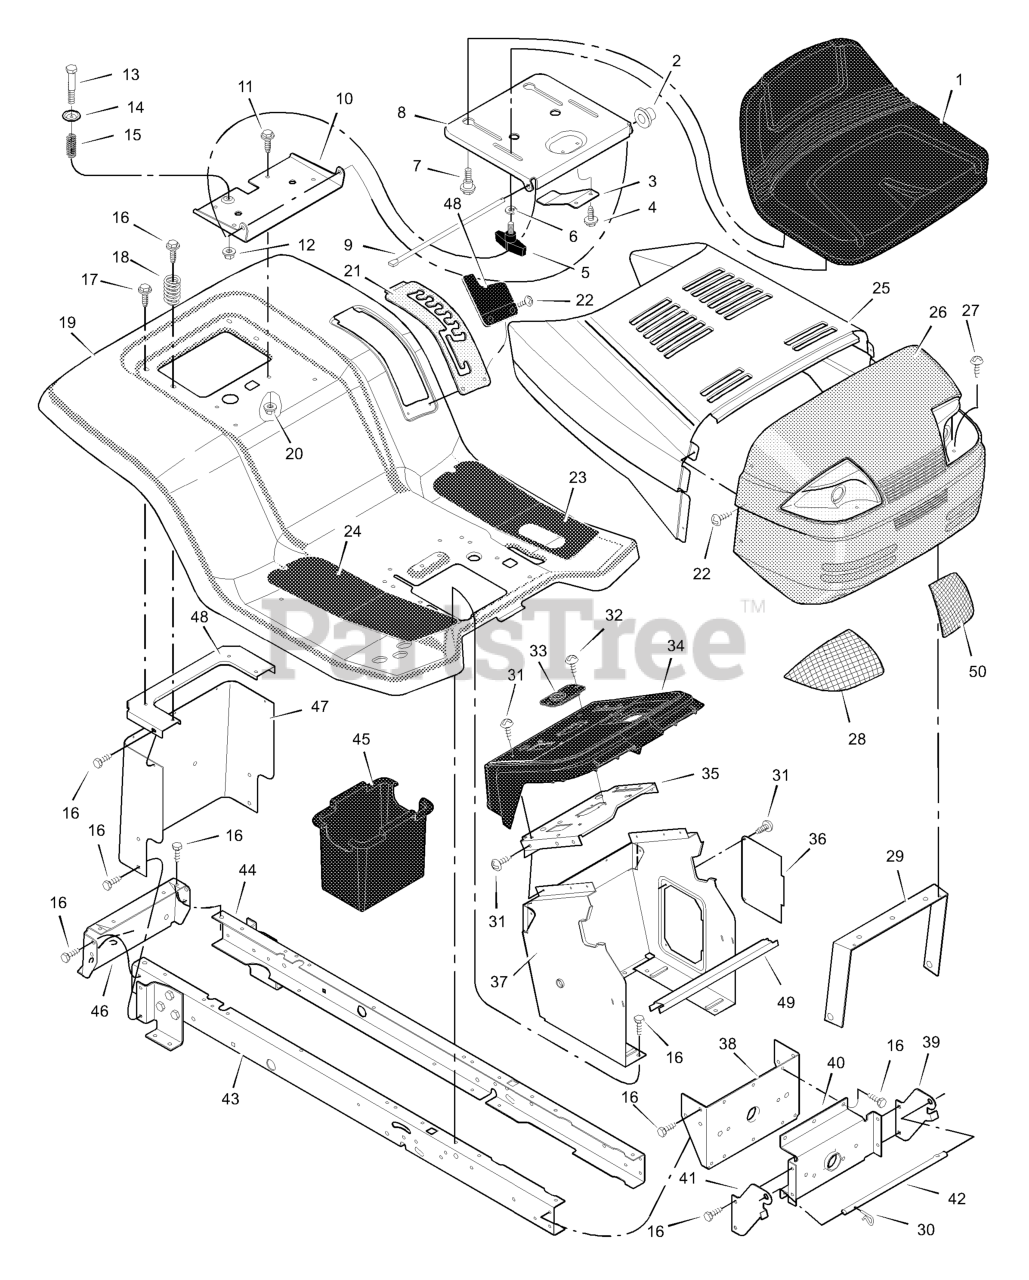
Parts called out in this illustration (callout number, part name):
2	Cap, Push On
5	Bolt, Wing
6	Washer
7	Bolt, Shoulder
8	Support, Seat
9	Rod, Pivot
10	Bracket, Pivot
11	Bolt
13	Bolt, Shoulder
15	Spring
19	Deck, Seat
20	Nut
21	Plate, Index
23	Mat, Left
24	Mat, Right
25	Hood
26	Grille Assembly
28	Lens, Right
29	Brace, Grille
30	Pin, Hair
31	Screw
33	Bearing, Steering
35	Plate, Dash
36	Panel, Access
37	Support, Dash
38	Bracket, Rear Hanger
39	Support, Left Grille
40	Axle, Hanger
41	Support, Right Grille
42	Rod, Pivot
43	Frame, Right
44	Frame, Left
45	Container, Battery
46	Plate, Hitch
47	Plate, Rear
48	Cover, Lift
50	Lens, Left
